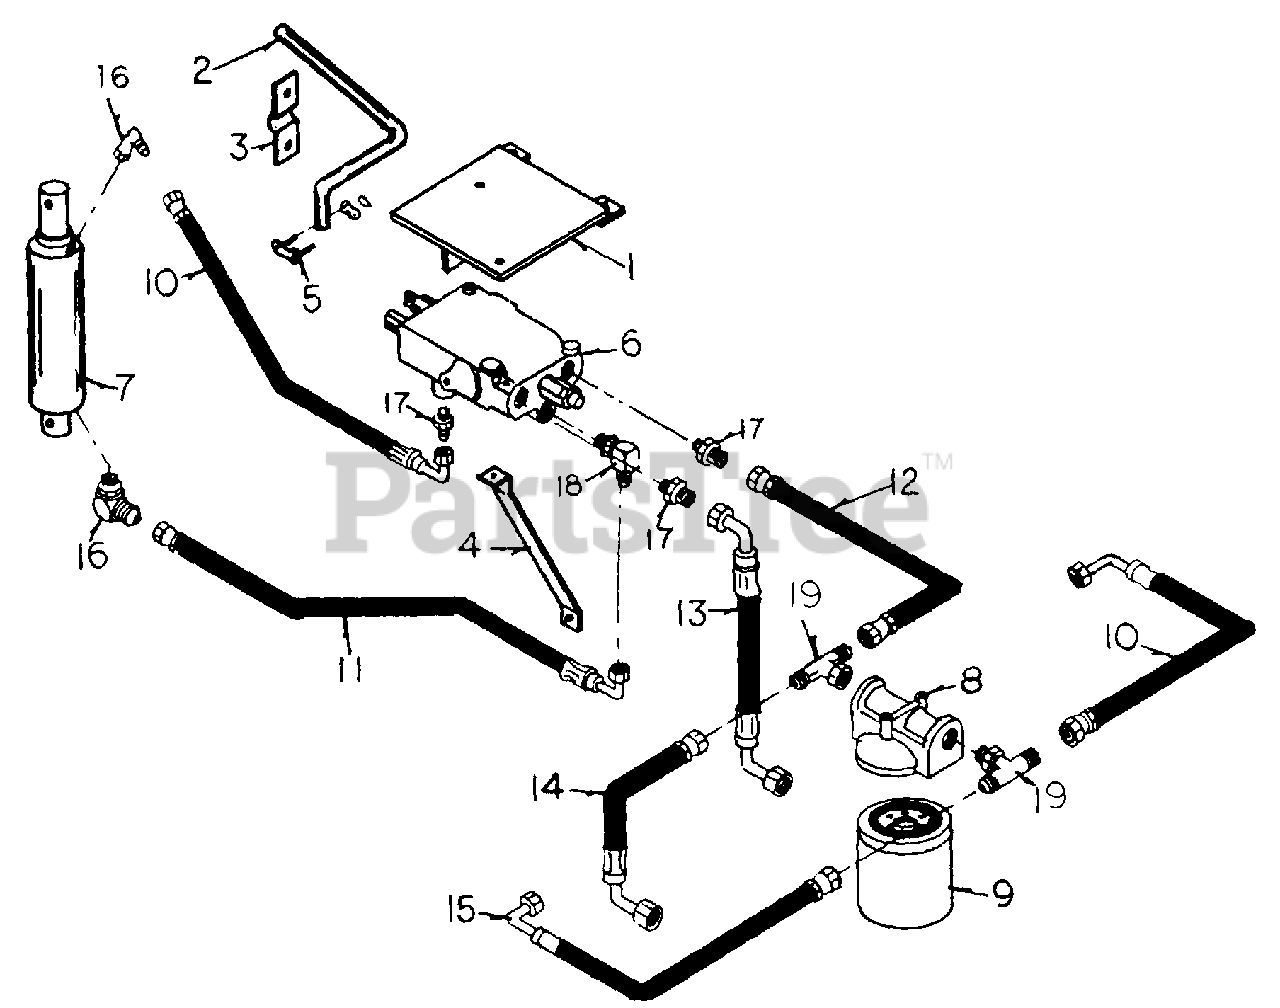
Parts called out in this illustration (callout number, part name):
1	MOUNT - valve
3	BEARING - clutch brake cross rod
4	SUPPORT valve
5	CONNECTING LINK - #50
8	HOUSING - oil filter
9	ELEMENT - oil filter
10	HOSE - 3/8" ID x 26" long
11	HOSE - 3/8" ID x 31" long
12	HOSE - 3/8" ID x 20" long
13	HOSE - 3/8" ID x 13" long
14	HOSE - 3/8" ID x 11.5" long
15	HOSE - 3/8" ID x 21" long
16	FITTING - male o-ring, 90° male tube adp.
17	FITTING - male o-ring, male tube adp.
18	FITTING - male o-ring, 90° male tube adp.
19	FITTING - male tube, male o-ring tee
